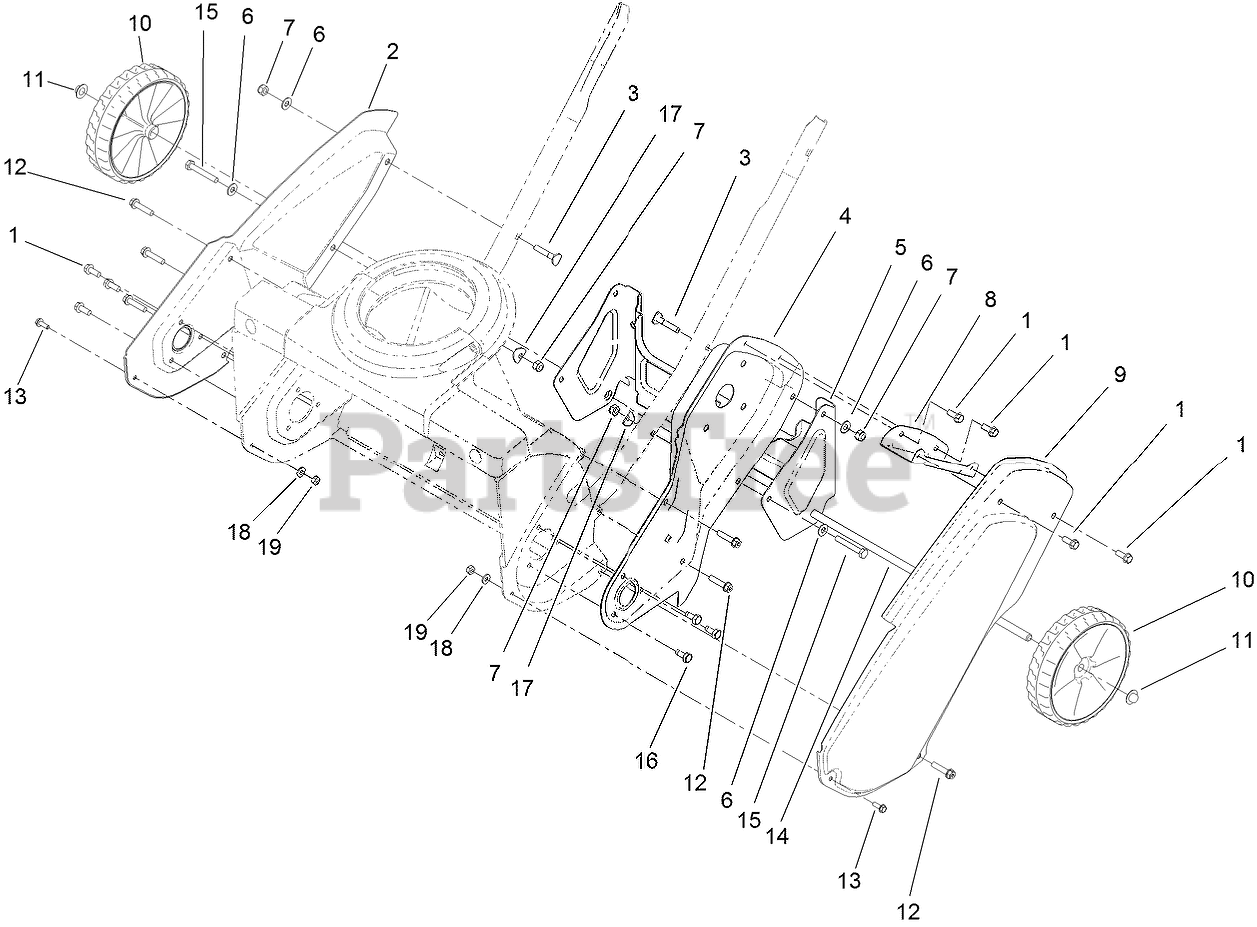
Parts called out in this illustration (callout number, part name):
1	SCREW-HWH
2	SIDEPLATE-RH
3	SCREW-HANDLE
4	SIDEPLATE-LH
5	BRACKET-WHEEL
6	WASHER-PLAIN
7	NUT-HEX
8	BRACKET-COVER, BELT
9	COVER-BELT
10	WHEEL ASM
11	NUT-PUSH
12	SCREW-PLASTIC,HWH
13	SCREW-HWH
15	SCREW-HH
16	SCREW-HH, TAPTITE
17	WASHER
18	WASHER-PLAIN
19	NUT-HEX
